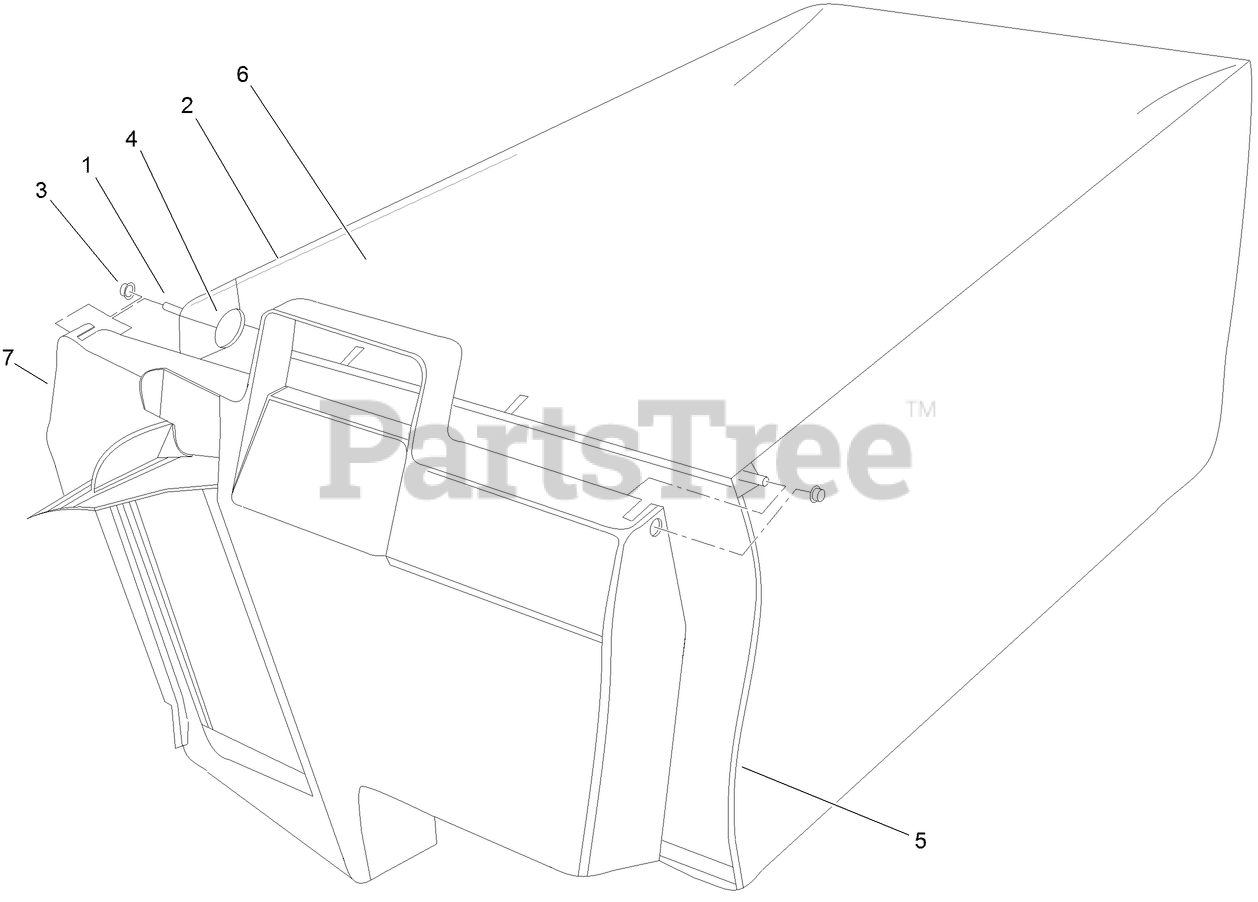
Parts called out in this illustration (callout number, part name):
1	HINGE-DOOR, BAG
2	FRAME-BAG, UPPER
3	NUT-PUSH
4	SPRING
5	FRAME-BAG
6	BAG-GRASS
7	DOOR-BAG, GRASS
